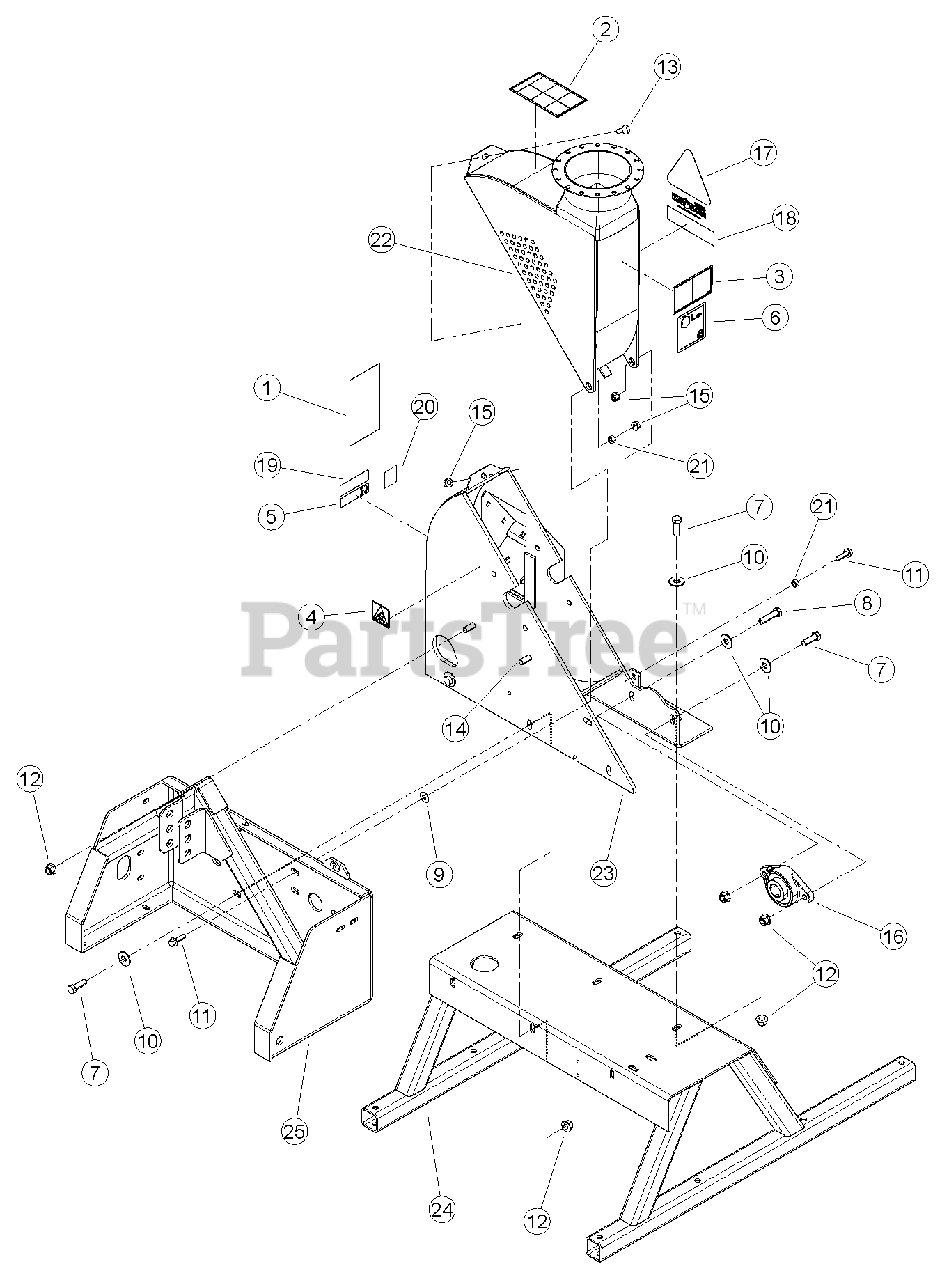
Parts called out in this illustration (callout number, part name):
1	DECAL, KNIFE ACCESS ISO
2	DECAL, OPERATING INSTRUCTIONS ISO
3	DECAL, DISCHARGE ISO
4	DECAL, SHIELD DANGER ISO
5	DECAL, 73454S INFORMATION
6	DECAL, 103 DB
7	BOLT, 1/2 X 1-1/2 HEX HD GR5 ZP
8	BOLT, 1/2 X 2 GR5 HEX CAPSCREW ZP
9	WASHER, 3/8" FLAT ZP
10	WASHER, 1/2" FLAT ZP
11	BOLT, 3/8 X 1-1/4 FLANGE NC
12	NUT, 1/2-13 NYLOCK FLANGE
13	BOLT, 3/8 X 1-1/4" GR5 CRG NC ZP
14	SCREW, 1/2 X 1-1/2 FLT HD SKT
15	NUT, 3/8-16 NYLOCK FLANGE
16	BEARING, 1-1/4" DIA 2 BOLT FLANGE
17	DECAL, CHIP IT
18	DECAL, MODEL CH5540
19	DECAL, ATLANTIC BRIDGE LTD INFO
20	DECAL, ECHO BEARCAT QR CODE
21	BUSHING
22	WELDMENT, CHIPPER TOP
23	WELDMENT, PTO CHIPPER BOTTOM
24	WELDMENT, PTO CHIPPER STAND
25	WELDMENT, CHIPPER HITCH
